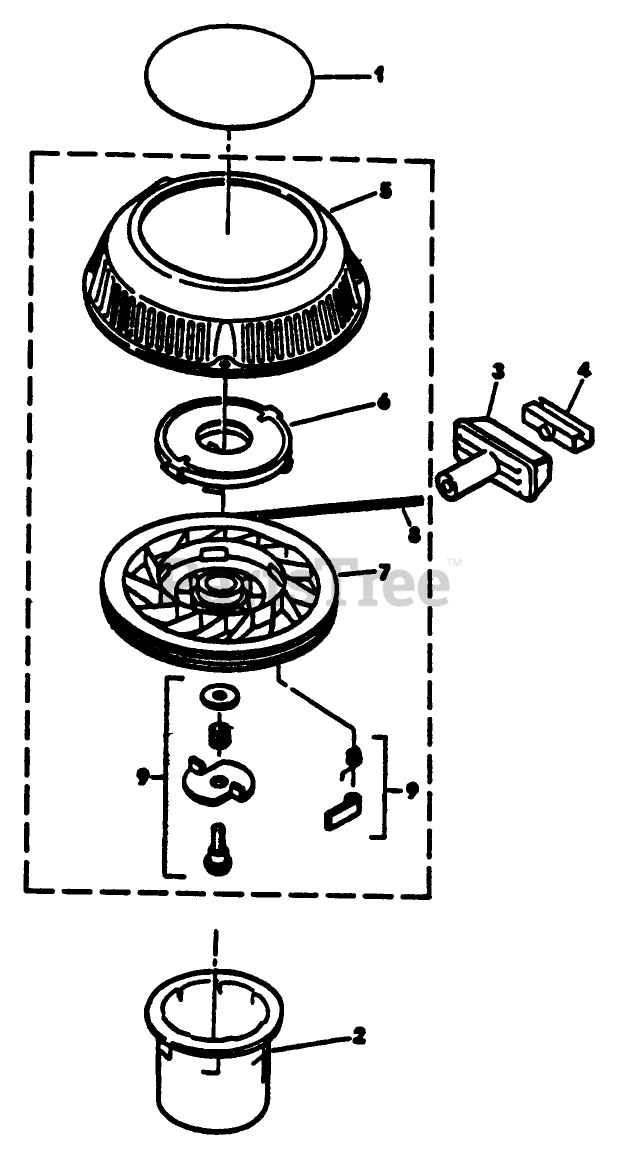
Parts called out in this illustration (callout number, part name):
2	HUB-STARTER E COMM.
4	CLIP-STARTER
5	STARTER HOUSING & SHAFT
9	DOG KIT
